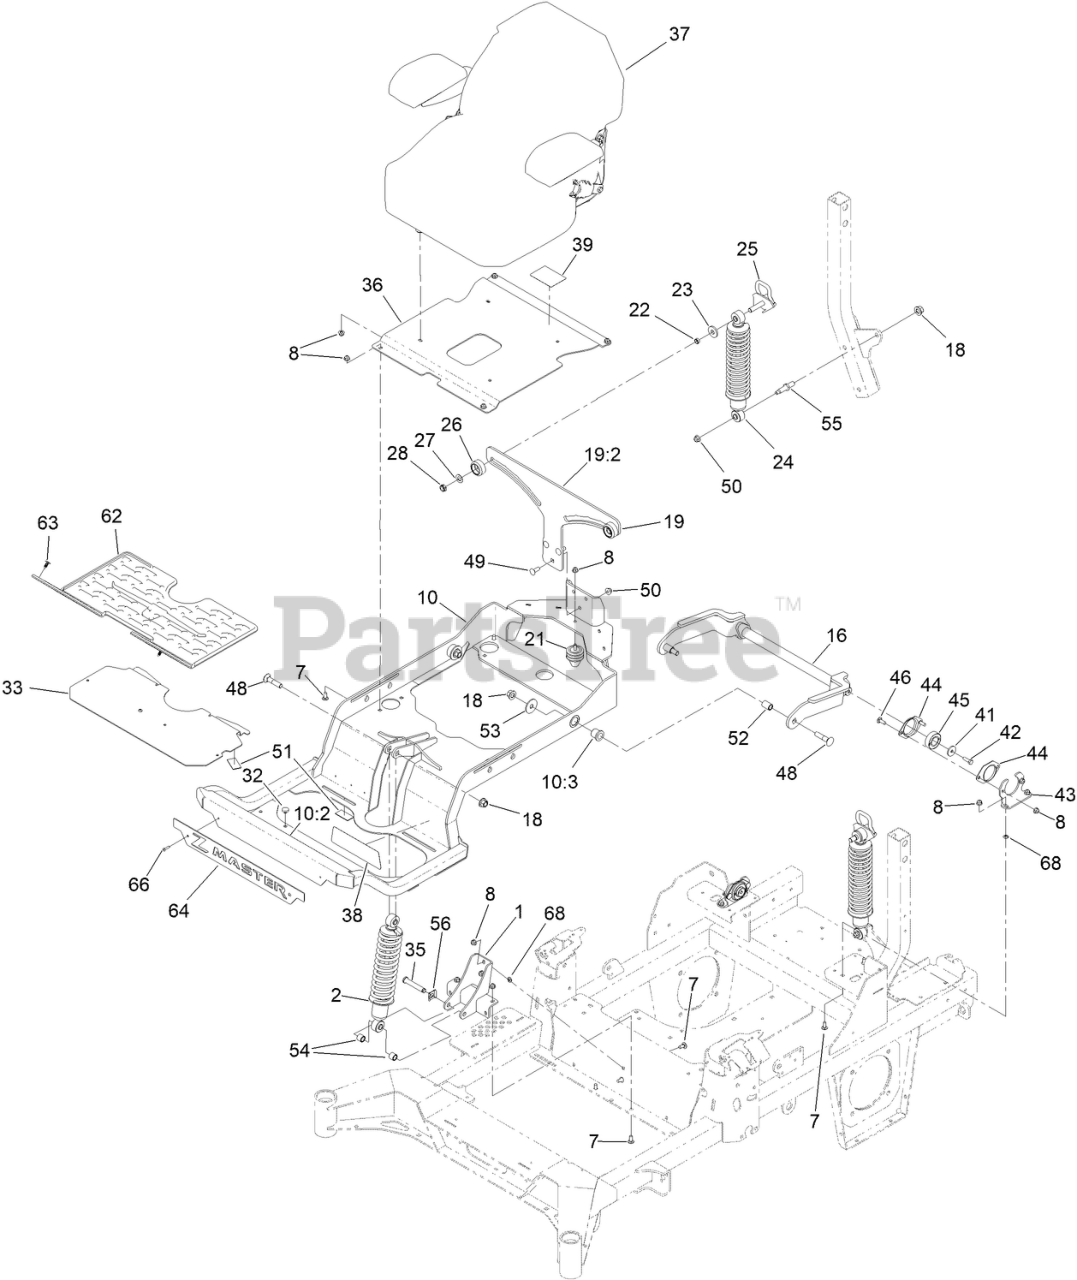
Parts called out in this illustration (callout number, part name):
1	MOUNT-SHOCK, LOWER [BLACK]
2	SHOCK ASM-FRONT
7	SCREW-CARR
8	NUT-HF, NI
10	SUBFRAME ASM
10:2	DECAL-DANGER
10:3	BUSHING-FLANGE
16	ARM-TRAILING
18	NUT-LOCK
19	BRACKET-MOUNTING
19:2	DECAL-ADJUSTMENT, RIDE
21	ISOLATOR
22	BEARING-SLEEVE
23	WASHER-PLASTIC
24	SHOCK/SPRING ASM
25	CAM LOCK ASM
26	KNOB-LOCK, CAM
27	WASHER-ADJUSTING
28	NUT-HEX
32	BUMPER
33	FLOORPAN
35	PIN-CLEVIS
36	PAN-SEAT
37	SEAT ASM-STANDARD
38	DECAL-MYRIDE
39	DECAL-SERVICE AID
41	WASHER-FLAT
42	SCREW-HH, THREAD LOCKING
43	BRACKET-BEARING
44	HOUSING-BEARING, FLANGE
45	BEARING
46	BOLT-CARR
48	SCREW-CARR
49	SCREW-CARR
50	NUT-HF, NI
51	PAD-RUBBER
52	SPACER-ALUMINUM
53	WASHER-THRUST
54	SPACER-TUBE
55	BOLT-SHOULDER
56	CLIP-PIN
62	FLOORMAT-MYRIDE
63	PLUG-PLASTIC
64	PLATE-BADGE [BLACK]
66	RIVET-TRIFOLD
68	NUT-PUSH
